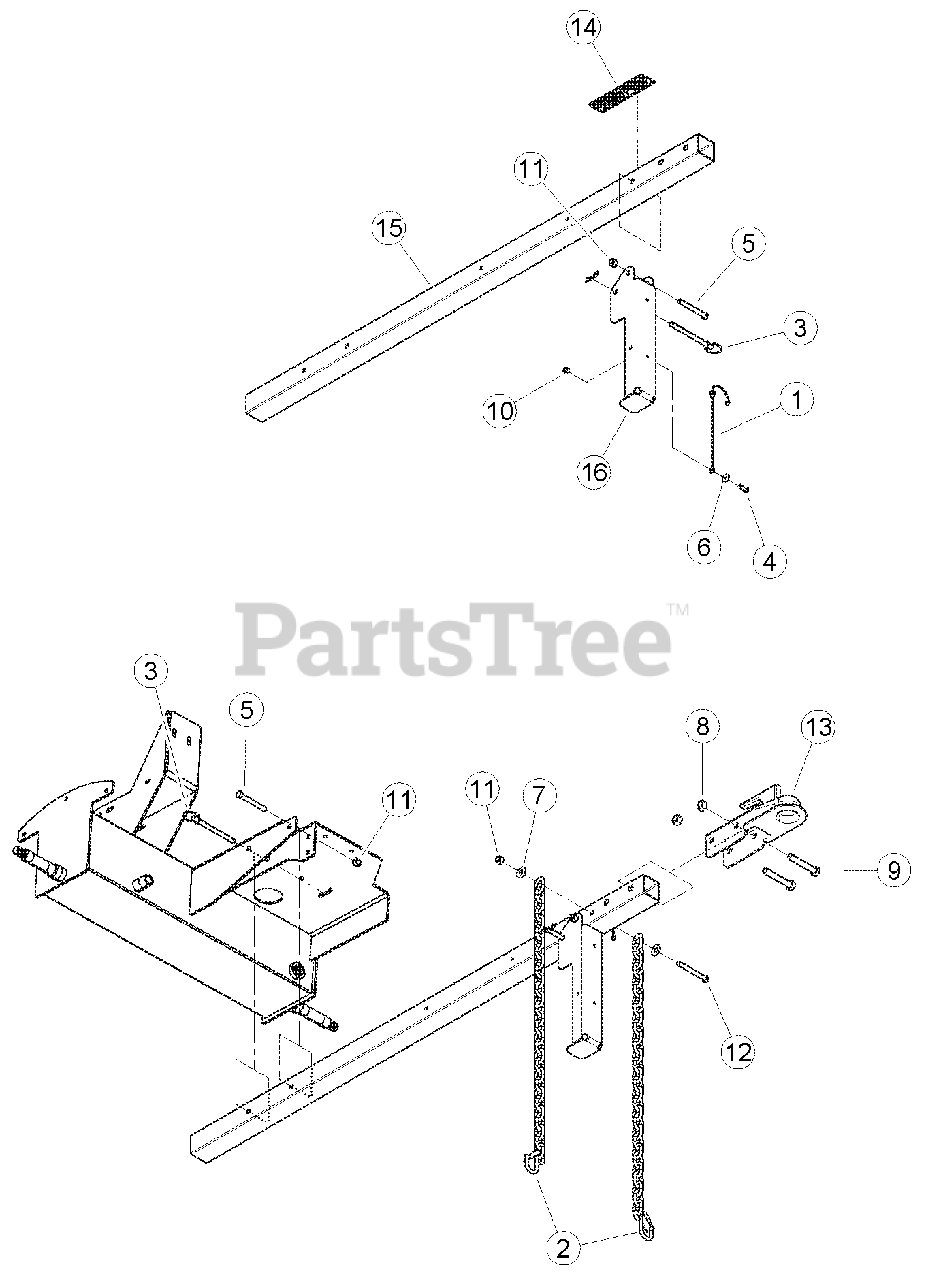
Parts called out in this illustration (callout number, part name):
1	LANYARD, NYLON
2	CHAIN, SAFETY 5000 LB W/LATCH
3	PIN, 3/8 HITCH
4	BOLT, 1/4 X 3/4 HEX HD GR5 ZP
5	BOLT, 3/8 X 3 HEX HD GR5 ZP
6	WASHER, 1/4 FLAT ZP
7	WASHER, 3/8 FLAT ZP
8	NUT, 1/2 CENTERLOCK GRB ZP
9	BOLT, 1/2 X 3 HEX HD GR5 ZP
10	NUT, 1/4 NE NYLOCK ZP
11	NUT, 3/8 NE NYLOCK ZP
12	BOLT, 3/8 X 3-1/4 HEX HD GR5 ZP
13	TRAILER HITCH COUPLER
14	DECAL, WARNING TOWING SPEED
15	TUBING, HITCH POLE
16	STAND, JACK
